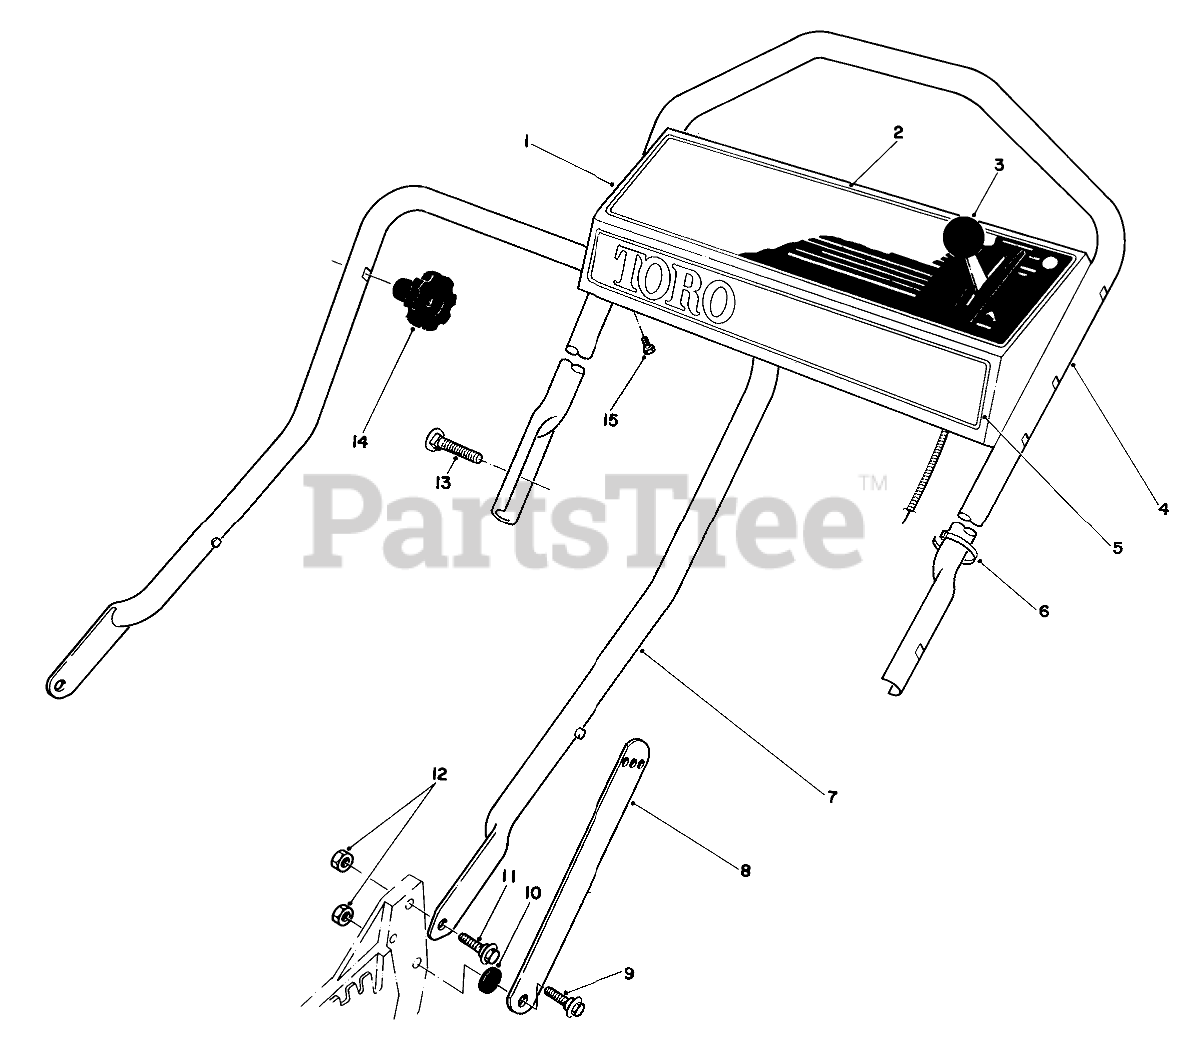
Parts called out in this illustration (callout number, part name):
1	Panel-Control (Incl. Ref. #2)
2	Decal-Instructions
3	SERVICE THROTTLE CONTRO
4	UPPER HANDLE
5	Decal-Toro
6	TIE-CABLE
7	Handle-Lower
8	Handle Latch
9	SCREW-SHOULDER
10	SPACER
11	SCREW-SHOULDER
12	NUT-LOCK, NI
13	5/16-18 X 2 HNDLE SCREW
15	SCREW-HWHTF
